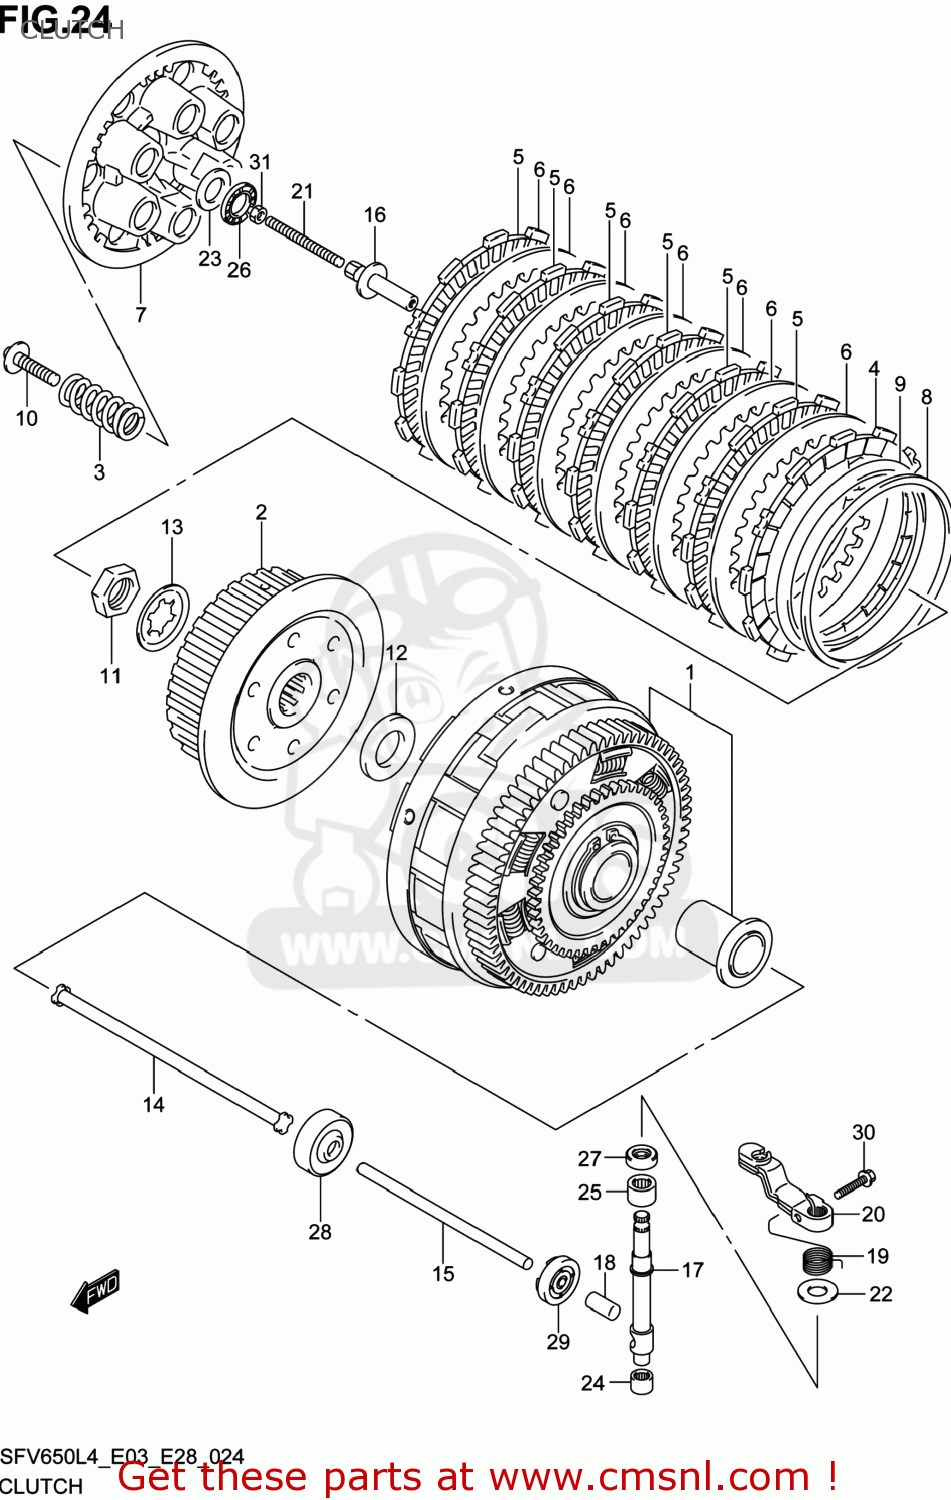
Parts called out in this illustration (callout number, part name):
1	GEAR ASSY,PRI DRIVEN
2	HUB,CLUTCH SLEEVE
3	SPRING,CLUTCH
4	PLATE,CLUTCH DRIVE NO.2 (NAS)
5	PLATE,CLUTCH DRIVE (NAS)
6	PLATE,CLUTCH DRIVEN(T:1.6) (NAS)
7	DISC,CLUTCH PRESSURE
8	SEAT,WAVE WASHER
9	WASHER,CLUTCH PLATE WAVE
10	BOLT(6X30)
11	NUT
12	WASHER(20X36X3)
13	WASHER,LOCK
14	ROD,PUSH,R
15	ROD,CLUTCH PUSH,L
16	PIECE,CLUTCH PUSH
17	CAMSHAFT,CLUTCH RELEASE
18	CAP,CLUTCH PUSH ROD
19	SPRING,CLUTCH RELEASE RETURN
20	ARM,CLUTCH RELEASE
21	SCREW(6X73)
22	WASHER(10.5X24X1)
23	WASHER(15.5X28X1)
24	BEARING(10X14X10)
25	BEARING(12X18X12)
26	BEARING(15X28X2)
27	SEAL,OIL(10X20X6)
28	SEAL,OIL(6X34X10.5)
29	SEAL,OIL(10X17X5)
30	BOLT
31	NUT
